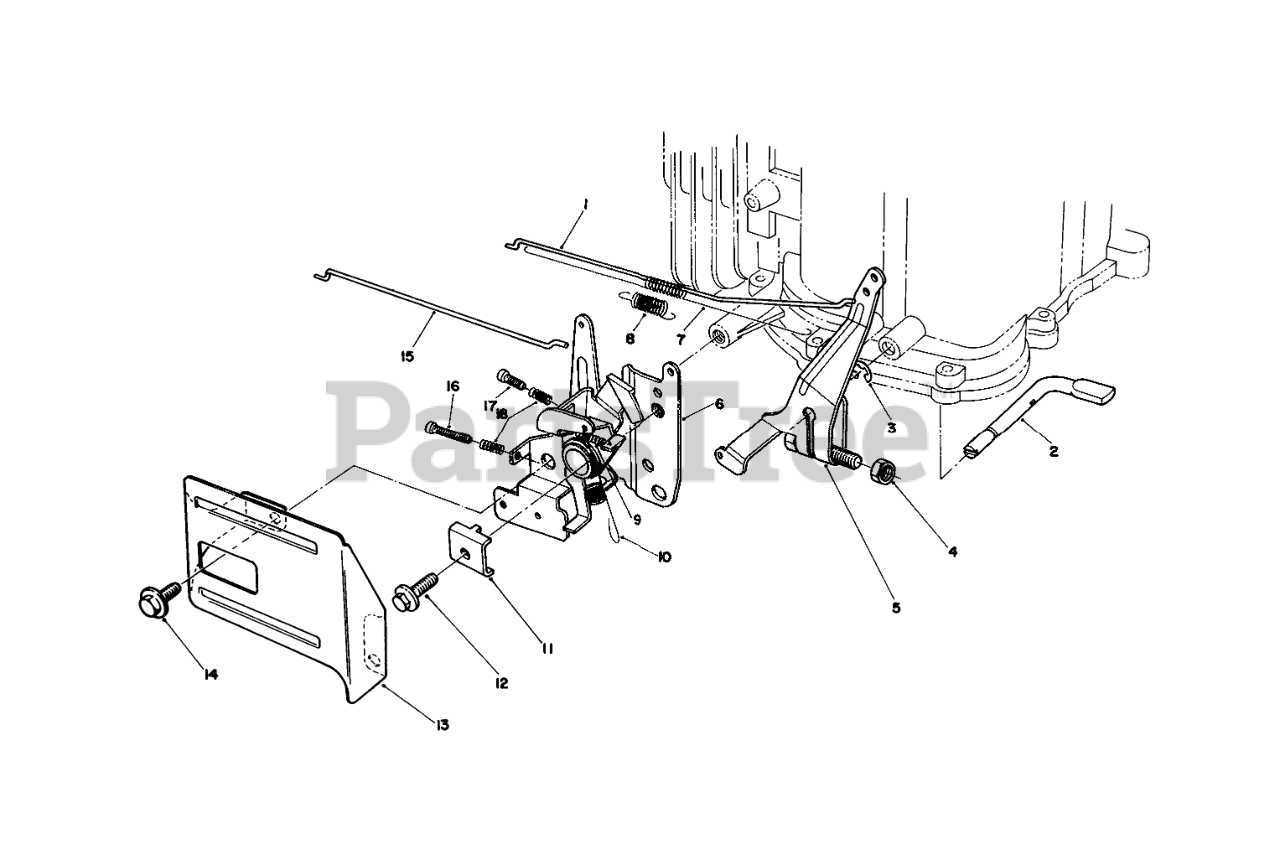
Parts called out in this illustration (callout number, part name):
1	Rod-Carburetor
2	SHAFT
3	E-RING
4	Nut
5	ARM ASM
6	THROTTLE
7	SPRING
8	SPRING
9	SPRING
10	SPRING
11	CLAMP-CABLE
13	THROTTLE GUARD
15	Rod-Choke
16	SCREW
17	SCREW
18	SPRING
